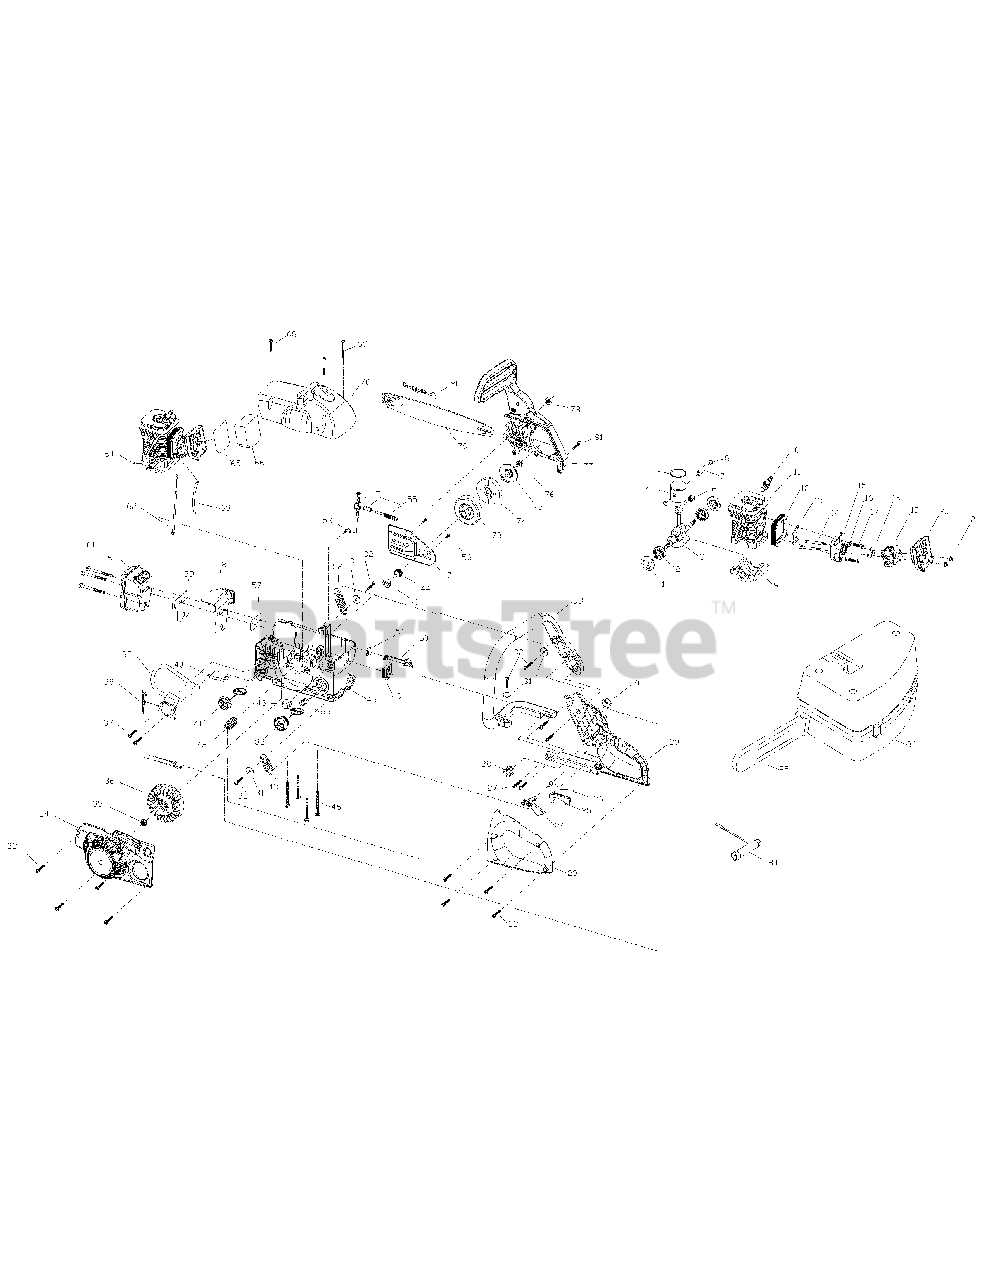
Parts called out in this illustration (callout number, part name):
1	CAP, BEARING
3	CRANK/ROD ASS'Y
5	RING, PISTON
6	ROLLER, PISTON
7	PIN, PISTON
9	CASE, CRANK
10	SPARK PLUG
12	RUBBER, ISOLATOR
15	ISOLATOR, CARBURETOR
16	SPRING WASHER
19	CARBURETOR
20	AIR FILTER ASS/Y
22	10/14-0.625SCREW
23	HANDLE, LEFT PART
24	TRIGGER, THROTTLE
25	TRIGGER, RELEASE
33	HANDLE, FRONT
34	STARTER HOUSING ASS'Y
38	WIRE ASS'Y
40	CONDUCTIVE PLATE
41	OIL CAP ASS'Y
42	SPRING ASS'Y
47	CAP, ANTI-DUST
48	HOUSING ASS'Y
49	HOLDER, CABLE
50	LEVER, CHOKE
51	HOLDER, CHOKE LEVEL
55	PUMP ASS'Y
60	MUFFLER ASS'Y
62	CABLE, THROTTLE
63	FUEL PIPE
64	WOODRUFF KEY
66	FILTER, AIR
73	DRUM ASS'Y
74	CLUTCH ASS'Y
75	CAP, ANTI-DUST
77	BRAKE KIT ASS'Y
82	FUEL CAP ASS'Y
86	CARRY CASE
